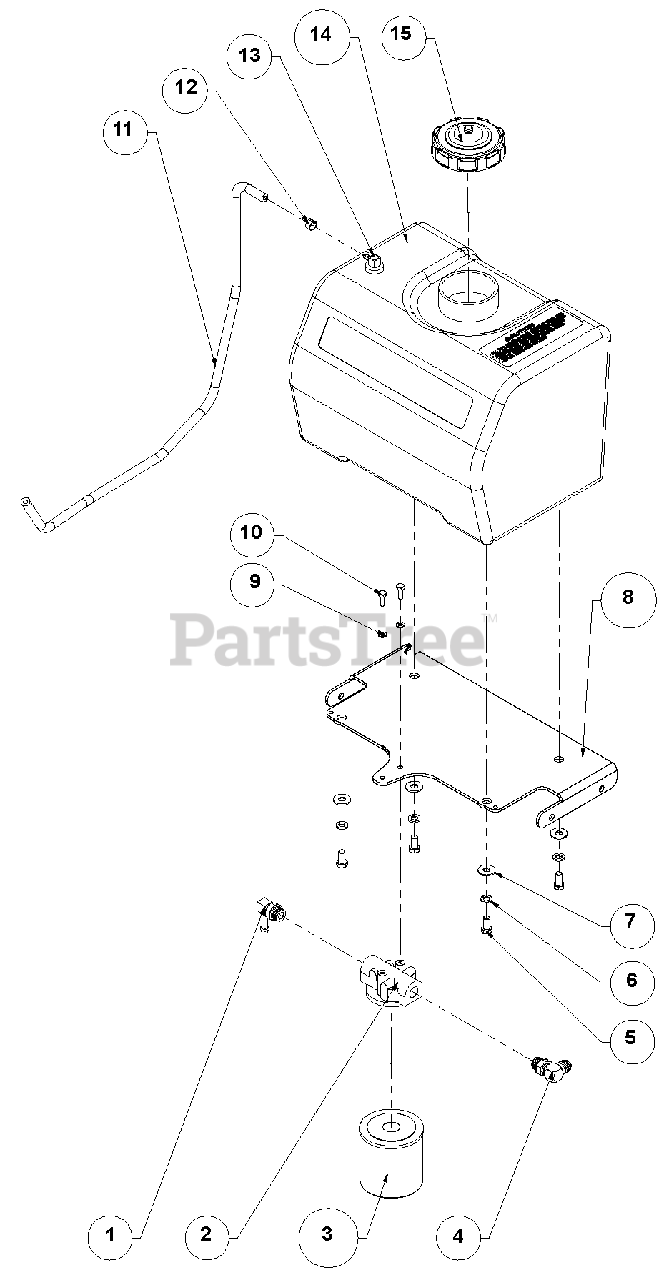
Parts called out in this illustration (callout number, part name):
1	Fitting, 90 BRB-OR
2	Head, Oil Filter
3	Filter, Oil
4	Fitting, 90 .75 MOR x .75 MJIC
5	Bolt, .38-16 x .750 Hex 5
6	Washer, .375 Medium Spring Lock
7	Washer, .375 Regular Flat
8	Bracket, Tank Support
9	Washer, .250 Medium Spring Lock
10	Bolt, 1/4-20 x .750 Hex 5
11	Hose, Fuel .25 x 30.00
12	Clamp, Hose- .50 Spring
13	Fitting, Tank
14	Tank, Fuel with Molded EverRide Decal
15	Cap, Fuel
